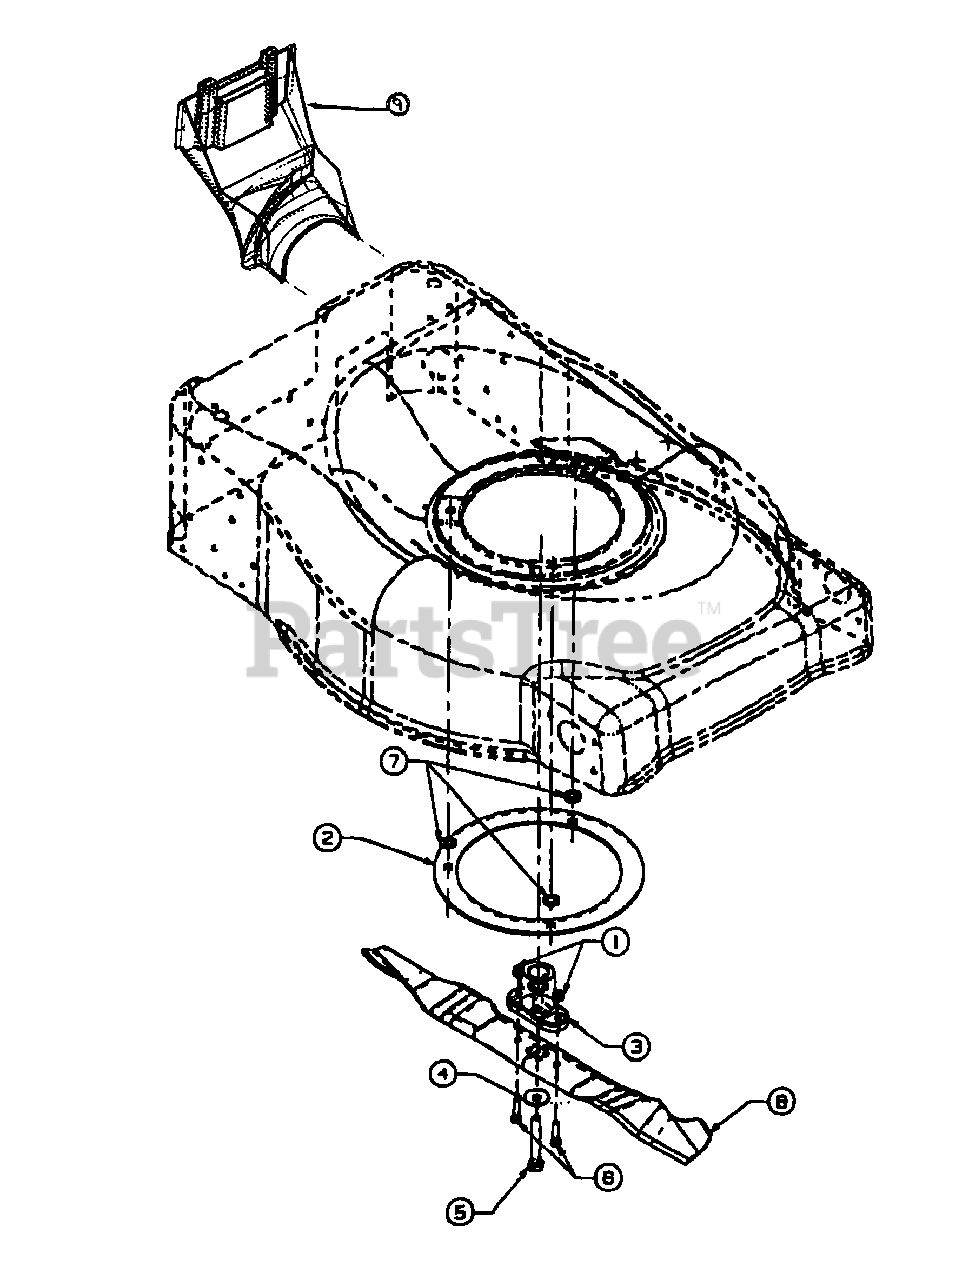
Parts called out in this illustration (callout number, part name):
1	NUT:HX:1/4-20:GRC:LOCK
2	PLATE-ENGINE: MOUNT:W/0 BBC
3	ADAPTER-BLADE:6 X 2.15 W/STAR
4	WASH:BELL: .396 X 1.140 X .095
5	SCREW-HEX CAP:3/8-24 X 2.50:GR8
6	SCREW-HEX CAP:1/4-20 X 1.00:GR5
7	WASHER-FLAT:3/8 X .738 X .063
8	BLADE:21": MULCHING: W/STAR
9	PLUG: MULCHER:RD:21"
